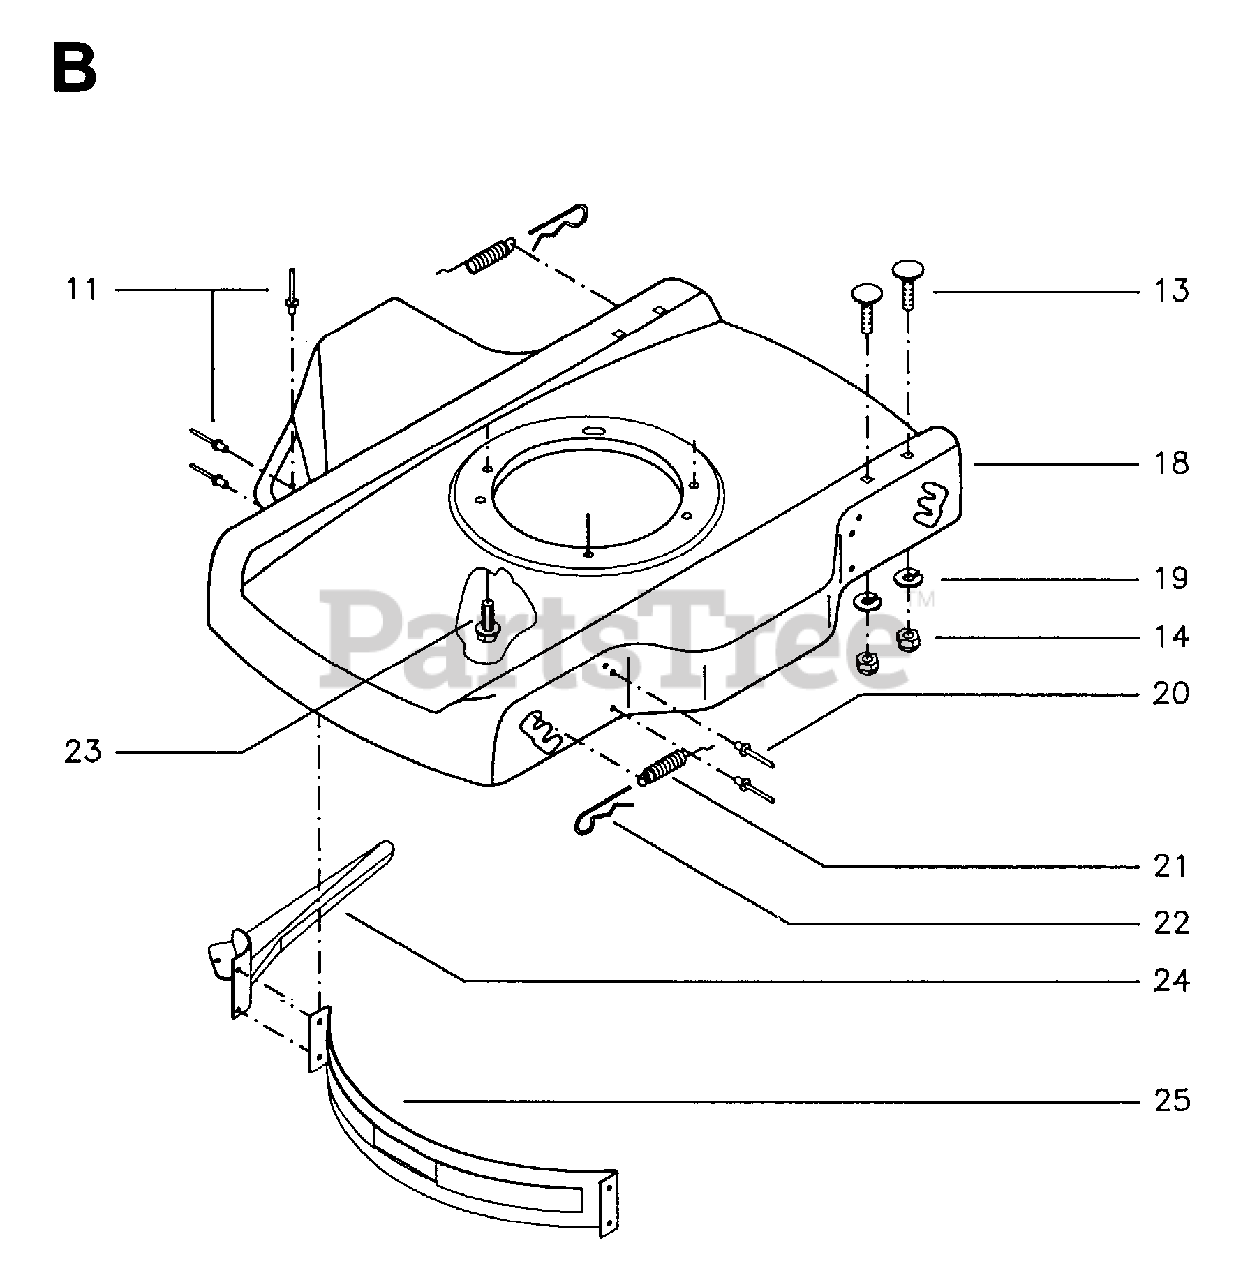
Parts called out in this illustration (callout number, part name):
14	NUT
19	SPRING WASHER
20	RIVET
